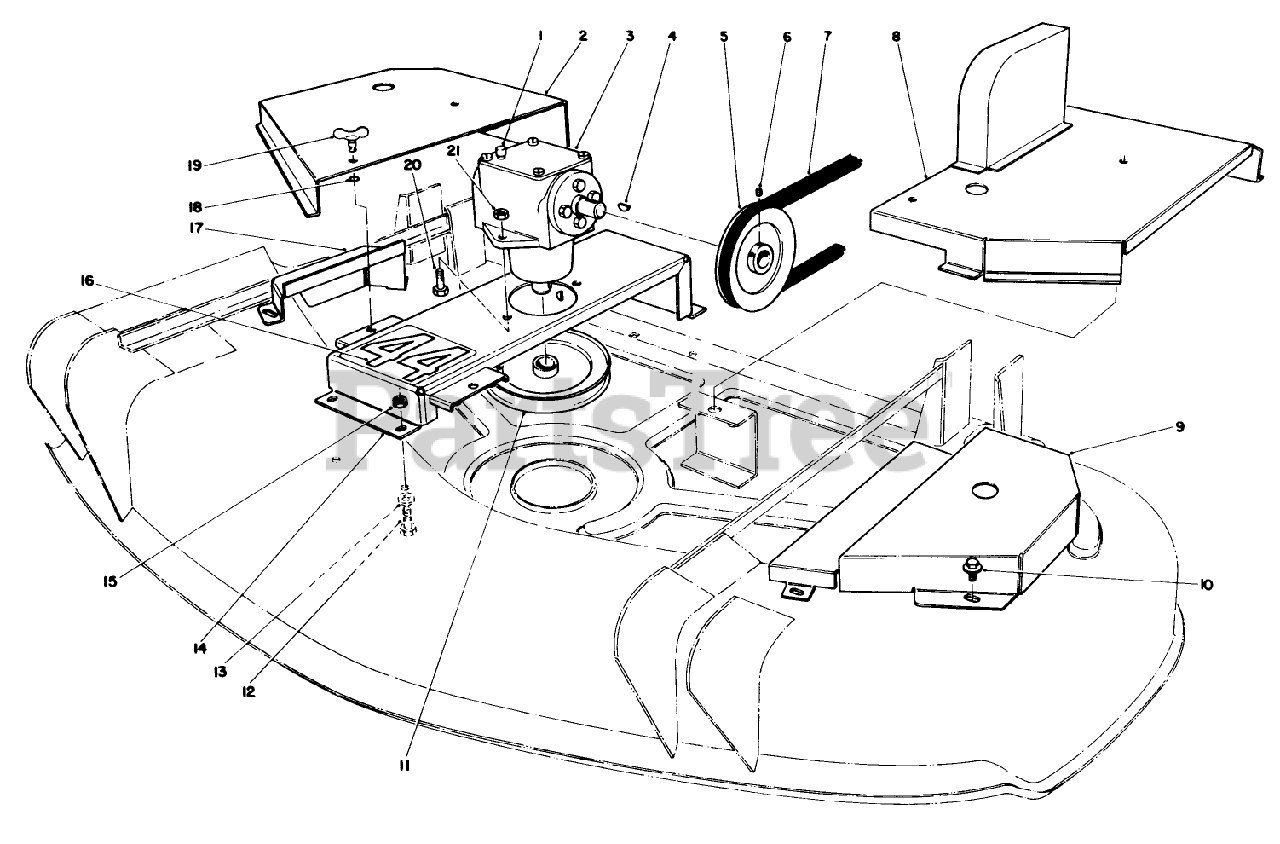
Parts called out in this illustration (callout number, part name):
2	Cover-Deck
3	GEARBOX-DRIVE, DECK
4	KEY-WOODRUFF
5	Pulley-Input (Incl. Ref. #6)
6	1/4-20 X 5/8 SETSCREW
7	V-BELT-DRIVE, DECK
8	Cover-Deck
9	Cover-LH
10	SCREW-HHFTF
11	Pulley-Output (Incl. Ref. #6)
12	SCREW-HH
13	WASHER-PLAIN
14	Bracket-Gearbox
15	NUT-LOCK, CONE
16	DECAL-44 INCH
17	Cover-RH
18	RING-SNAP
19	STUD-HEAD, WING
20	SCREW-HH
21	NUT-LOCK, CONE
